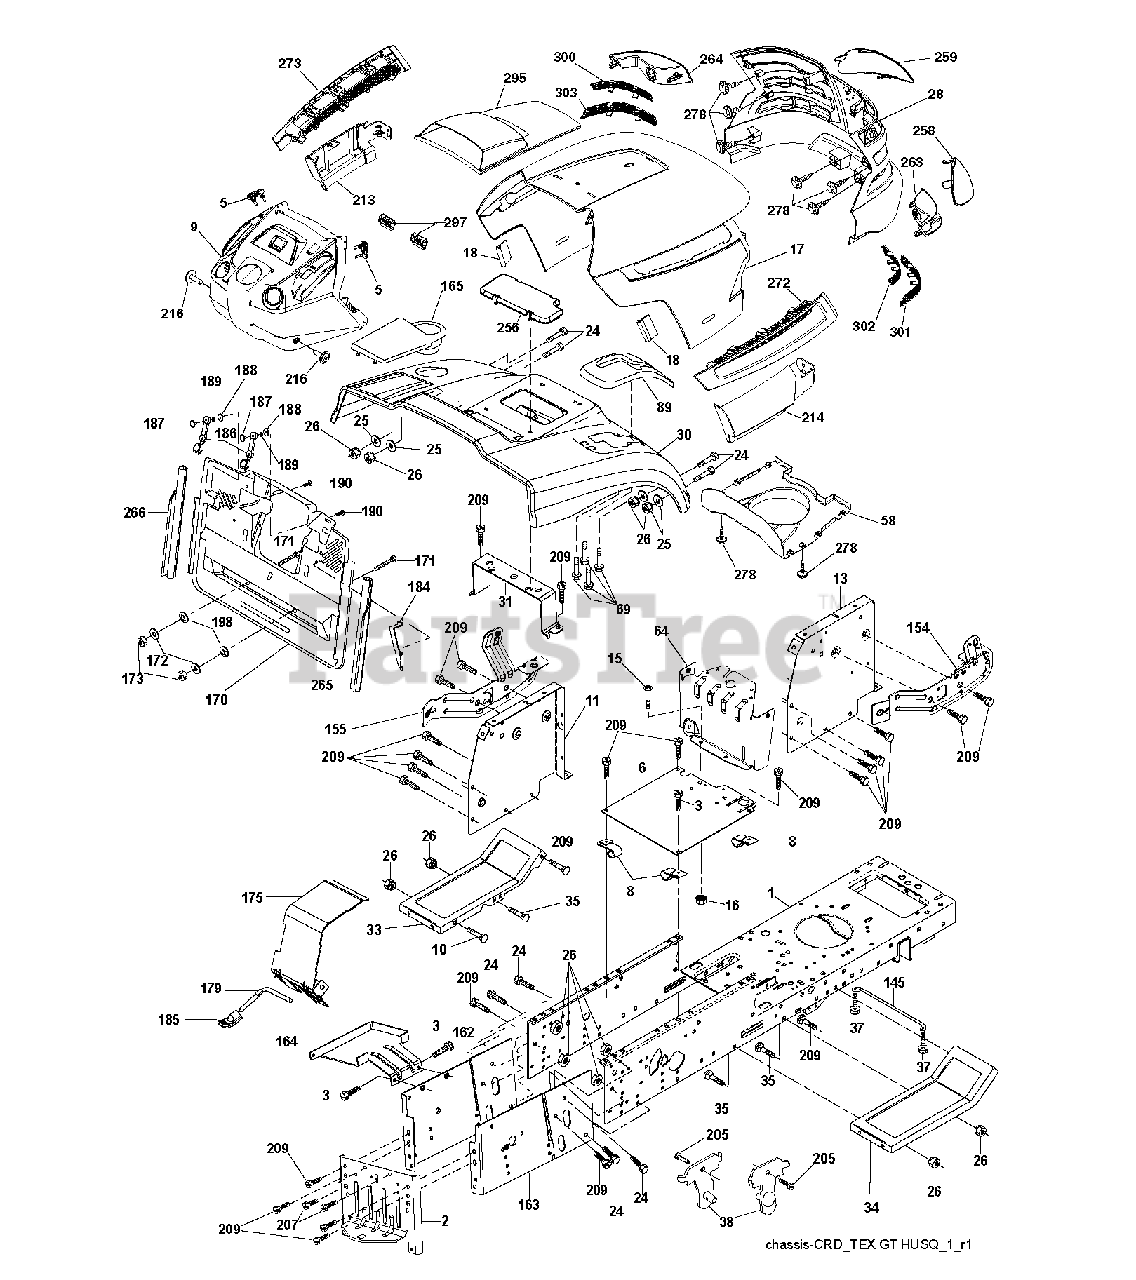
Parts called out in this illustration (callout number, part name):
2	DRAWBAR
3	SCREW 3/8-16X3/4
5	BUMPER DASH
6	PLATE
8	CLIP,INSULATOR
10	BOLT D
11	PANEL DASH LH
13	PANEL DASH RH
16	NUT
17	HOOD.ASM.HUSQVARNA.GT.TEX.ORAN
18	BUMPER.HOOD.TEX.HUSQVARNA
25	WASHER
26	NUT
28	GRILL.ASM.HUSQ.TG/CRD.W/TRIM
30	FENDER.PNT.CRD.MS-668
31	BRACKET SUPPORT FENDER
33	FOOTREST.PNT.LH.GREY
34	FOOTREST.PNT.RH.GREY
37	SCREW LT
38	BRACKET ASM PIVOT MOWER REAR
58	AIR.DUCT.HOOD.TEX.GT.HUSQ
69	SCREW.HI-LO.CONSOLE
89	CONSOLE.CRD.AUTO.GRY
145	ROD.PIVOT.HOOD
162	BRACKET
163	BRACKET EXTEN CHASSIS RH CRD
165	COVER.BATTERY.BAG.ELE.CRD.498
172	WASHER
175	DOOR TRAP
179	ROD PIVOT FBI
184	BRACKET.ACTUATOR.BAGGER.SRD
185	KNOB.BRAKE.PARKING.ROD
186	LATCH ASSY
187	WELDNUT
189	LOCKWASHER (3 2)
190	SCREW
207	SCREW, 5/16-18 X 1/2
209	SCREW, 3/8-16X3/4
213	SKIRT.HOOD.SIDE.HUSQ.L
214	HOOD SIDE SKIRT RH
216	SCREW 14-20 X 5/8
256	FENDER.PNT.CRD
258	LENS.RH.TEX.GT.HUSQ.CL
259	LENS.LH.TEX.GT.HUSQ.CL
263	BEZEL.RH.TEX.GT.HUSQ
264	BEZEL.LH.TEX.GT.HUSQ
265	SEALING
266	SEALING
272	VENT.SIDE.HOOD.RH.HUSQ
273	VENT,SIDE.HOOD.LH.HUSQ
278	SCREW.#10 X 0.750.BOS
295	HOOD VENT
297	CLIP.RETAINER.TINNER.
300	INSERT.HEX.GRILL.HUSQ.
301	INSERT.HEX.GRILL.HUSQ.GREY
302	INSERT.HEX.GRILL.HUSQ.
303	INSERT.HEX.GRILL.HUSQ.
